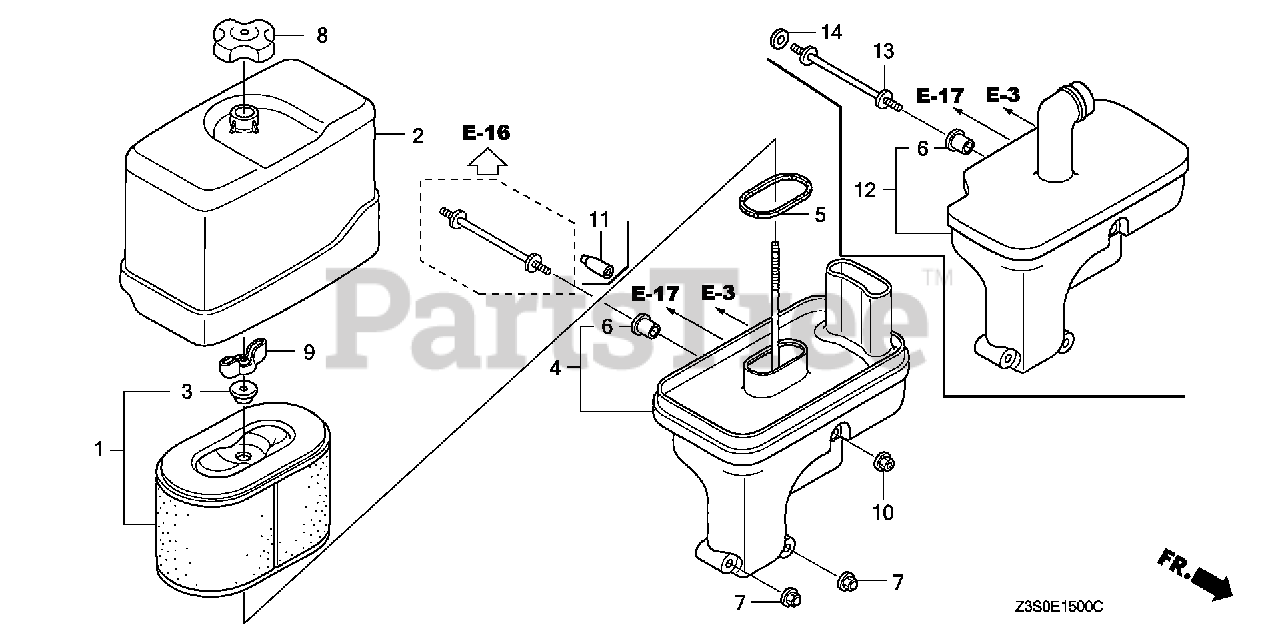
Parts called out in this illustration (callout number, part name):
1	ELEMENT, AIR CLEANER
2	COVER, AIR CLEANER
3	GROMMET, AIR CLEANER
4	ELBOW, AIR CLEANER
5	GASKET, AIR CLEANER ELBOW
6	COLLAR, FAN COVER (Honda Code 5580527). (N/A: SEE ASSEMBLY)
7	NUT, CAP (6MM)
8	NUT, AIR CLEANER COVER
9	WINGNUT, TOOL BOX SETTING
10	NUT, FLANGE (6MM)
